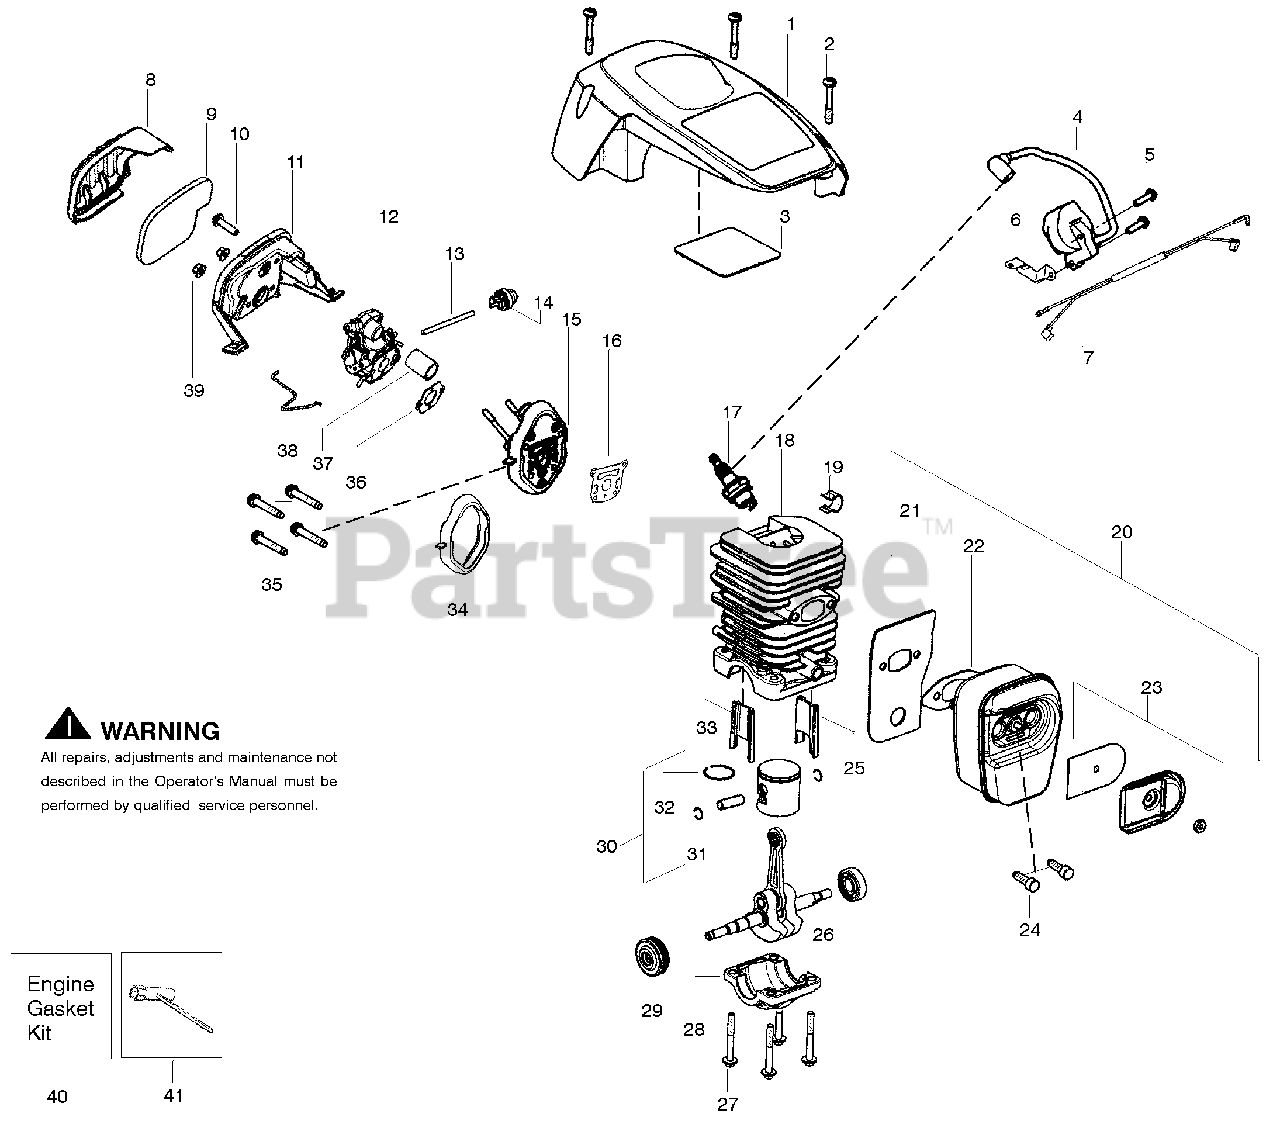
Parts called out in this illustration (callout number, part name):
1	Shield-Cylinder
3	Reflector-Tape
4	Module - Ignition
6	Strap-Ground
7	Assy-Wire Harness
8	Cover-Air Filter
9	Filter-Air
11	Housing-Air Filter
12	Carburetor Walbro WTA30
12	Carburetor Zama W-26B
13	Kit-Fuel Line (Small)
14	Bulb-Purge "snap-in"
15	Kit-Carb. Adaptor
16	Gasket-cyl. o-ring (kit)
17	Accy-Spark Plug (RCJ-7Y)
18	Kit-Cylinder
19	Clip-High Tension Lead
20	Kit-Muffler
21	Backplate-Muffler
22	Gasket-Muffler (kit)
23	Kit-Spark Arrestor
24	Bolt-Muffler
25	Insert-Left (black) Cyl.
26	Assy-Crankshaft/Rod
28	Cap-Crankcase
29	Assy-Bearing/Seal
30	Kit-Piston
31	Retainer-Piston Pin
32	Ring-Piston
33	Insert-Right (gray) Cyl.
34	Seal-Adaptor (kit)
36	Gasket-Carb. (kit)
37	Tube-Intake
38	Wire-Throttle
39	Nut-Carb.
40	Kit-Gasket
41	Scrench
